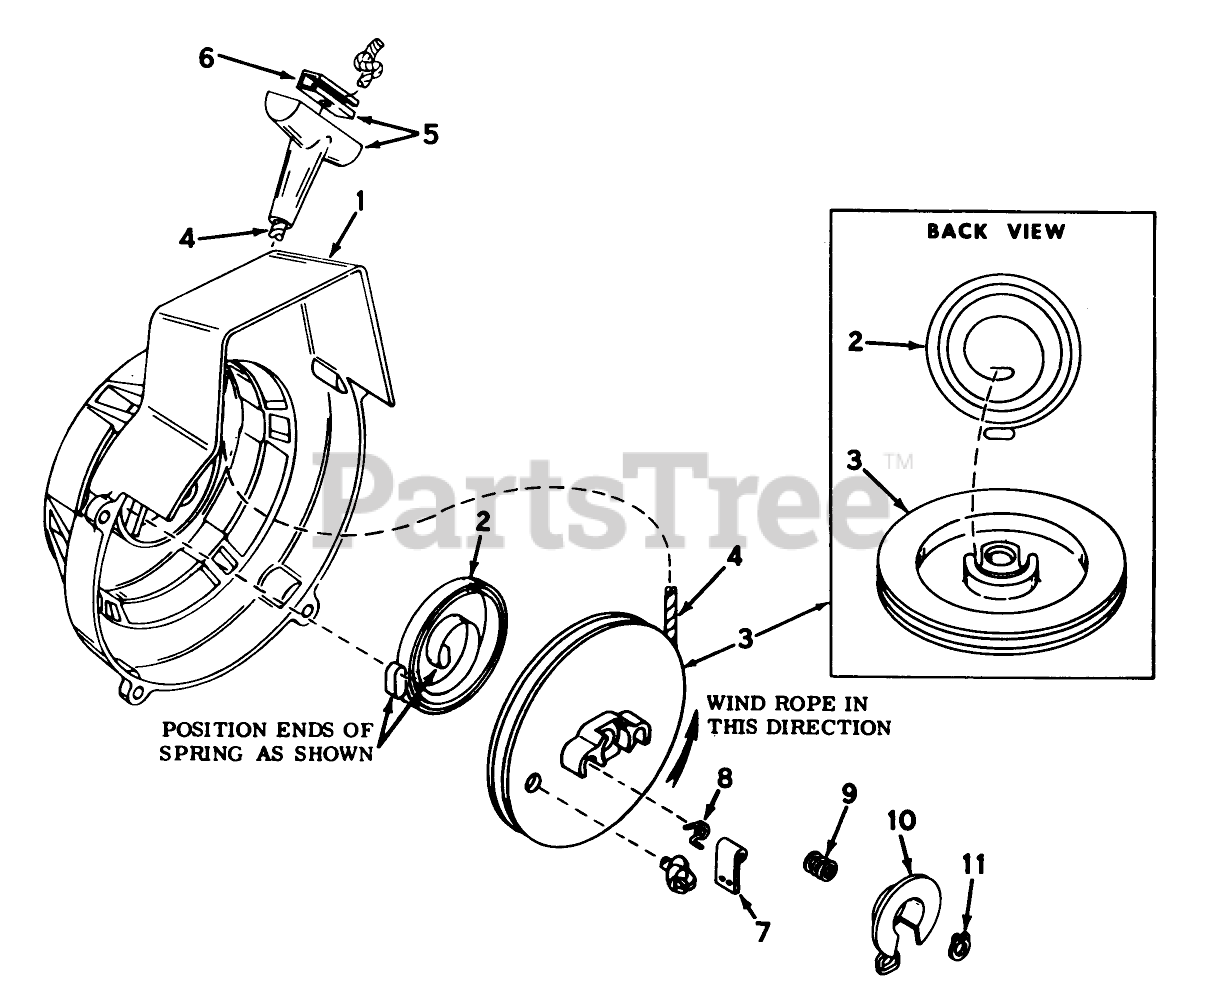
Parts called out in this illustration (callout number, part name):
1	Housing Assy., Shroud Starter
2	Spring, Rewind
3	Pulley, Starter Rope(Incl. No. 8)
4	Rope, Starter
5	Assy., Starter
6	Insert, Handle
7	Dog, Starter
8	Retum Spring, Left Hand Wound
9	Spring, Brake
10	Brake
11	E Ring Truarc
